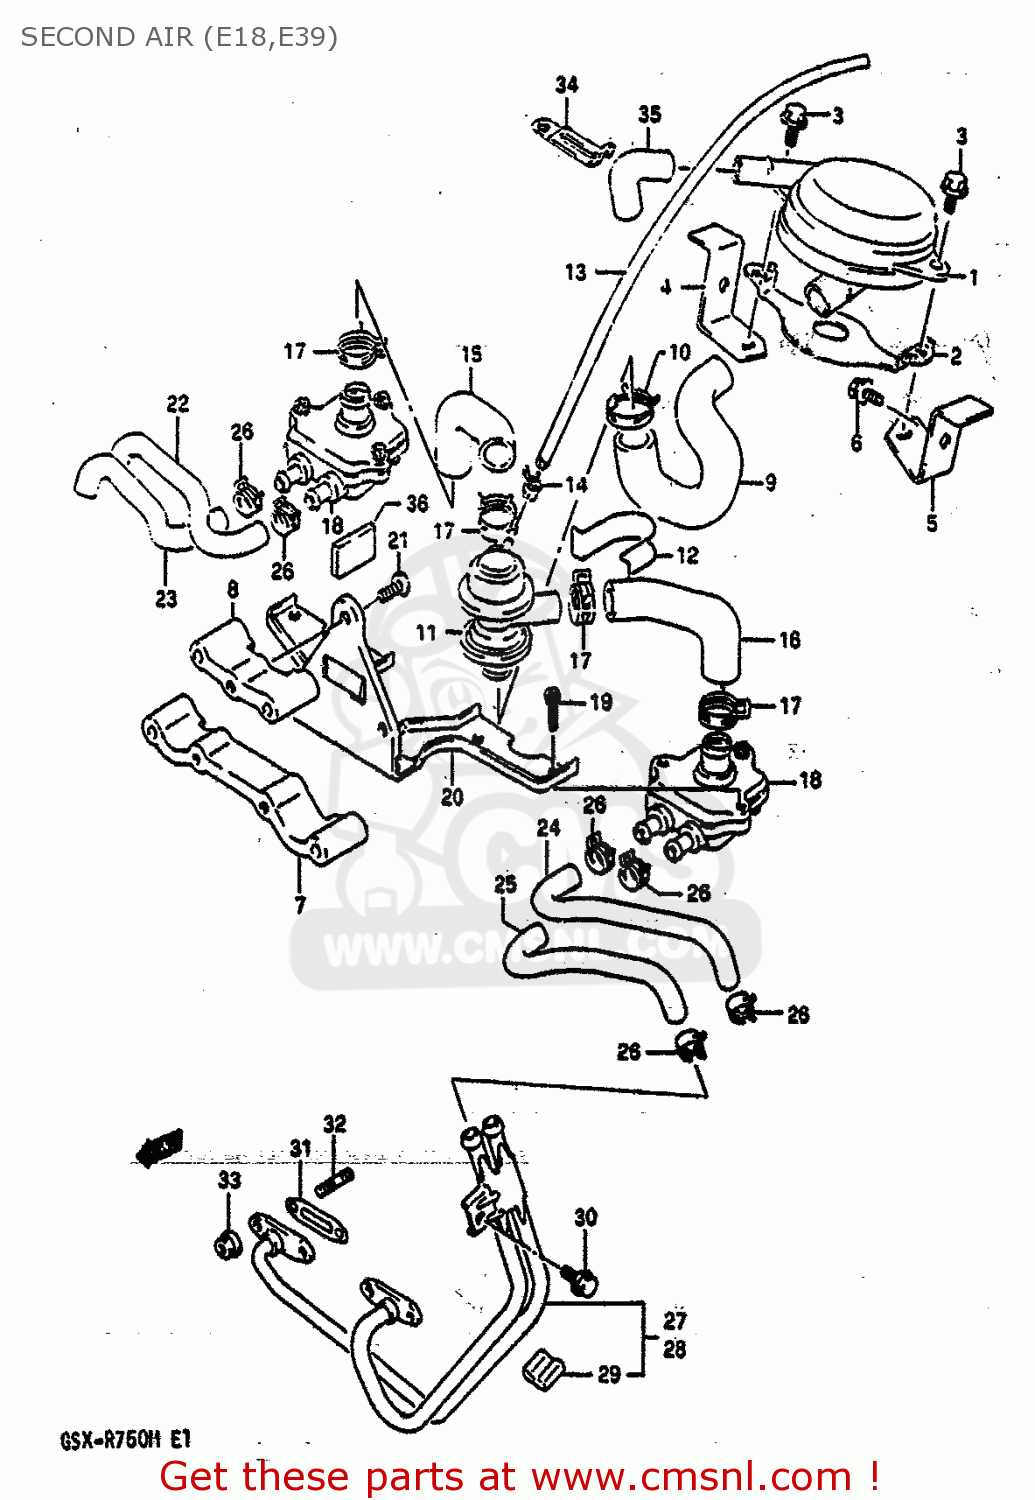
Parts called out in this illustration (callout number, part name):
1	CLEANER ASSEMBLY,SECOND AIR
2	HOLDER,SECOND AIR CLEANER
3	BOLT
4	BRACKET,AIR CLEANER,RH
5	BRACKET,SECOND AIR CLEANER
6	BOLT
7	SPACER,SECOND AIR BRACKET,LOWER
8	SPACER,SECOND AIR BRACKET,UPPER
9	HOSE,SECOND AIR NO.3
10	CLIP
11	VALVE ASSEMBLY,AIR SWITCH
12	CLAMP,SWITCHING VALVE
13	HOSE
14	CLAMP
15	HOSE,SECOND AIR NO.2,RIGHT
16	HOSE,SECOND AIR NO.2,LEFT
17	CLIP
18	VALVE ASSY,2ND AIR REED
19	BOLT
20	BRACKET,SECOND AIR VALVE
21	SCREW
22	HOSE,SECOND AIR NO.1,RIGHT,INLET
23	HOSE,SECOND AIR NO.1,RIGHT,OUTLET
24	HOSE,SECOND AIR NO.1,LEFT,INLET
25	HOSE,SECOND AIR NO.1,LEFT,OUTLET
26	CLIP
27	PIPE,SECOND AIR,RIGHT
28	PIPE,SECOND AIR,LEFT
29	(CA) CUSHION
30	BOLT 6X12
31	GASKET,SECOND AIR PIPE (NAS)
32	STUD BOLT
33	NUT 6MM
34	CLAMP L:35
35	(CA) HOSE,SECOND AIR CLEANER
36	CUSHION
